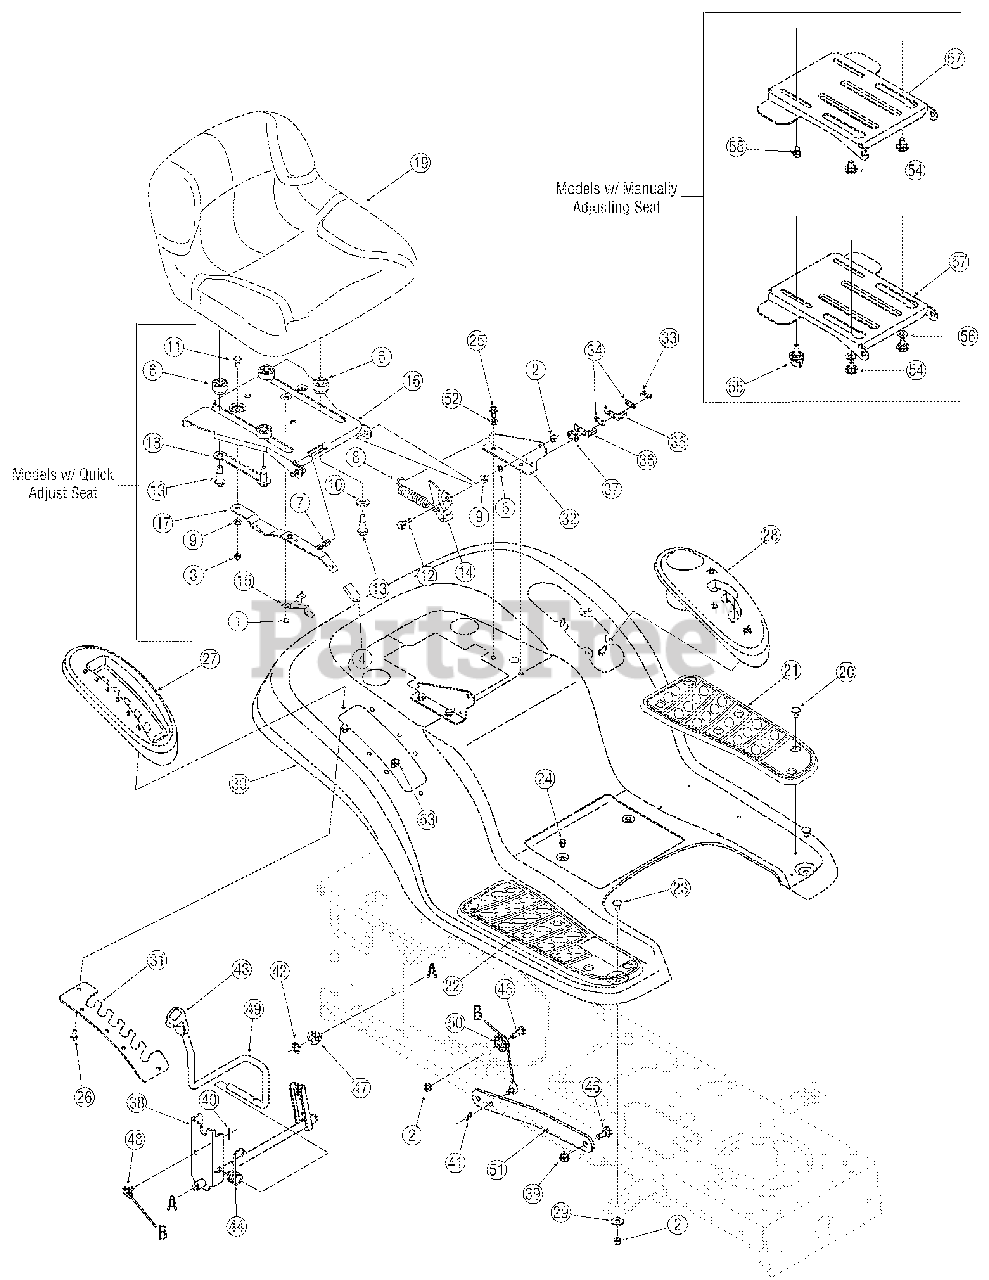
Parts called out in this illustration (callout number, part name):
1	Screw, #10-16 x.375
2	Nut, Flange Lock, 5/16-18, GrF
3	Nut, Flange Lock, 1/4-20
4	Seat Adjuster Grip
5	Nut, Speed,.3125 ID
6	Spacer
7	Compression Spring,.41 x 1.5
8	Spring, Extension,.84 Dia. x 4.6
9	Wash, Flat,.344 x.688 x.065
10	Wash, Flat,.531x 1.062 x.134
11	Screw, Shld, .340 x.285, 1/4-20
12	Screw, Shoulder,.437 x.268
13	Screw, Should,.50 x.925, 3/8-16
14	Seat Bracket, Lift
15	Seat Stop
18	Seat Adjustment Selector
19	Medium Back Seat
20	Ratchet Clip
21	LH Foot Pad, Rubber
22	RH Foot Pad,Rubber
23	Bolt, Carriage, 5/16-18,.75, Gr1
24	Screw, 1/4-20, 0.500
25	Screw, 5/16-18, 0.625
26	Screw, 1/4-15, 0.750
27	Cover, Lift Lever
28	Cover, w/ Cup Holder
29	Washer, Flat,.344 x 1.0 x.063
33	Screw, #8-18 x.50
34	Plate, Insulator
35	Spring Switch, Outer
36	Spring Switch, Inner
37	Plate, Insulator Boss
38	Shaft Assembly, Lift
39	Nut, Flange Lock, 3/8-16, GrF
40	Pin, Cotter,.072 Dia. x 1.13
41	Pin, Cotter, 3/32, 1.0
42	Ring, E Type,.625 Dia.
43	Grip, Handle, 1/2
44	Spring, Torsion
45	Screw, 5/16-18 x.620 Gr2
46	Screw, Shld,.50 x.27
47	Bearing, Hex Flange
48	Cable, Lift, 16.16
49	Handle, Lift
50	Pulley, Roller
52	Lock Washer, 5/16
53	Screw, 5/16-12
54	Shoulder Screw
55	Knob, 3/8-16
56	Flat Washer, .406 x .875
58	Hex Head Washer Screw, 3/8-16
